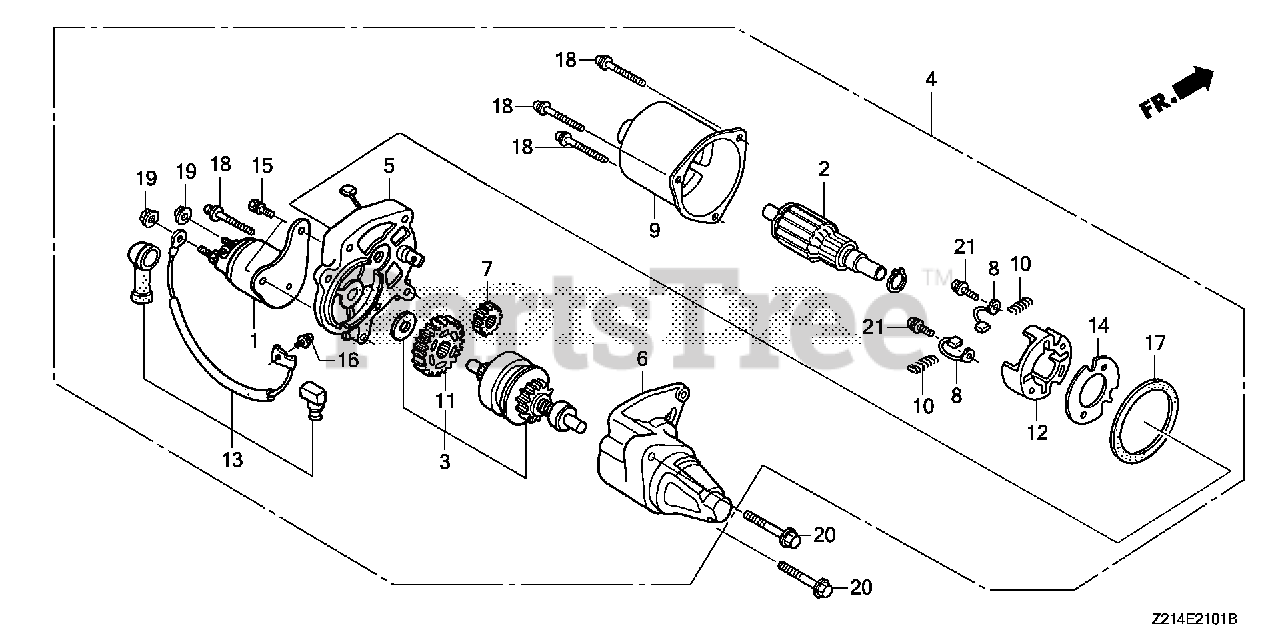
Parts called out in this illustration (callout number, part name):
1	CONTACTOR ASSY.
2	ARMATURE
3	CLUTCH, OVERRUNNING
4	STARTER MOTOR UNIT
5	BRACKET, CENTER
6	BRACKET, FR.
7	GEAR, DRIVE PINION
8	BRUSH
9	YOKE
10	SPRING, BRUSH RETURN
11	GEAR, REDUCTION
12	HOLDER, BRUSH
13	WIRE, WATER COVER
14	INSULATOR
15	BOLT-WASHER (5X14)
16	SCREW-WASHER (4X6)
17	GASKET
18	SCREW-WASHER (5X3)
19	NUT-WASHER (6MM)
20	BOLT, FLANGE (8X35)
21	SCREW-WASHER (4X14)
